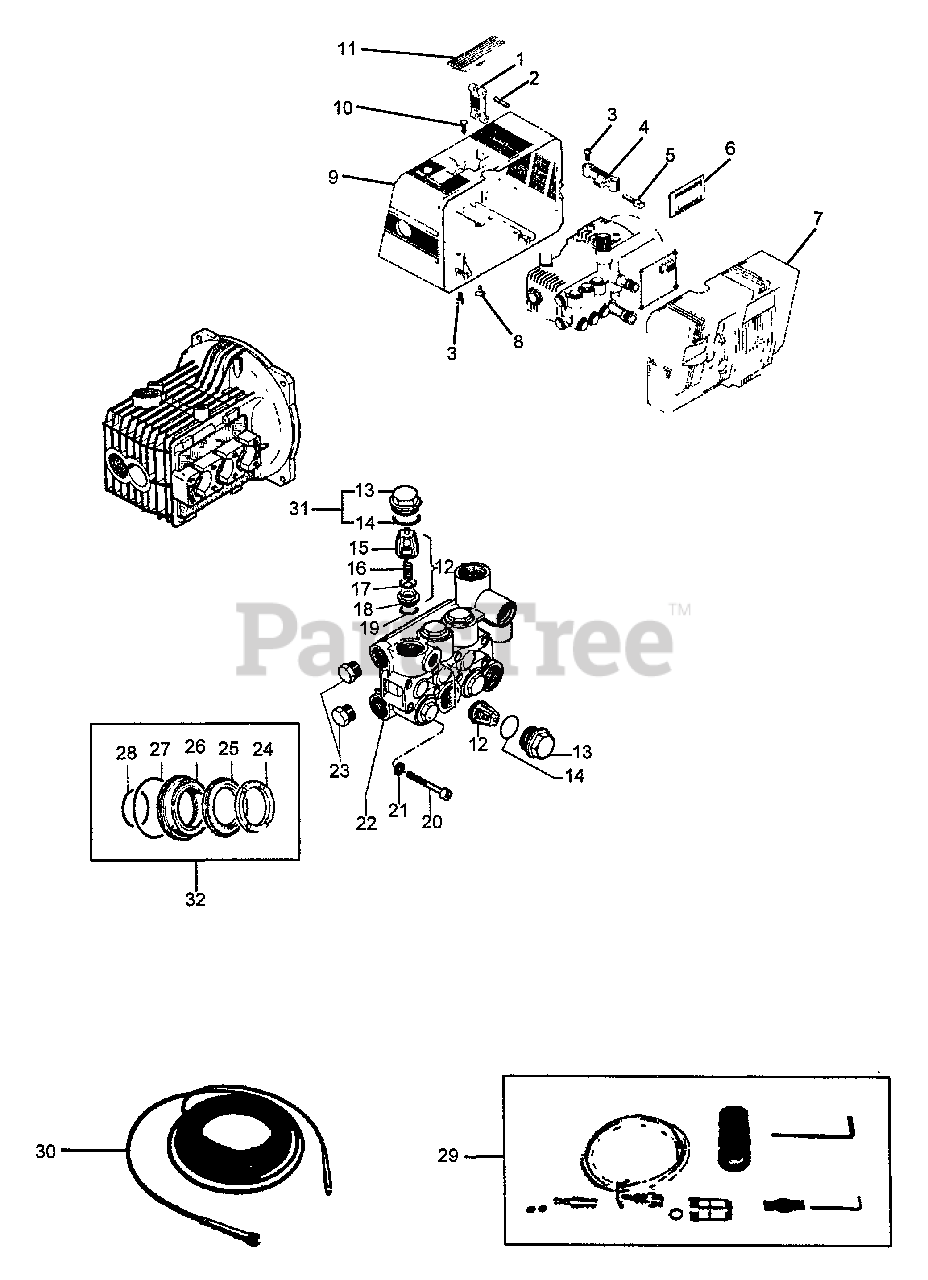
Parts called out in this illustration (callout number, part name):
1	ARM, HANDLE
2	PIN, 8.5 X 34
3	SCREW - 8X16
4	PLATE, HANDLE RETAINER
5	PIN, HANDLE RETAINER
6	PLATE, ON-OFF
7	COVER - FRONT
8	PLUG
9	COVER - REAR
10	SCREW - 4X13
11	HANDLE
12	VALVE KIT
13	CAP
14	O-RING - .797 X.103
15	GUIDE, VALVE
16	SPRING
17	PLATE, VALVE
18	SEAT, VALVE
20	SCREW - 6X40
21	LOCKWASHER - 6
22	MANIFOLD
23	CAP, OIL DRAIN PLUG
24	RING, HEAD
25	PACKING
26	RETAINING, PACKING
27	O-RING
28	O-RING
29	ACCESSORY KIT
30	HOSE - 8M
31	VALVE KIT
32	PACKING KIT
